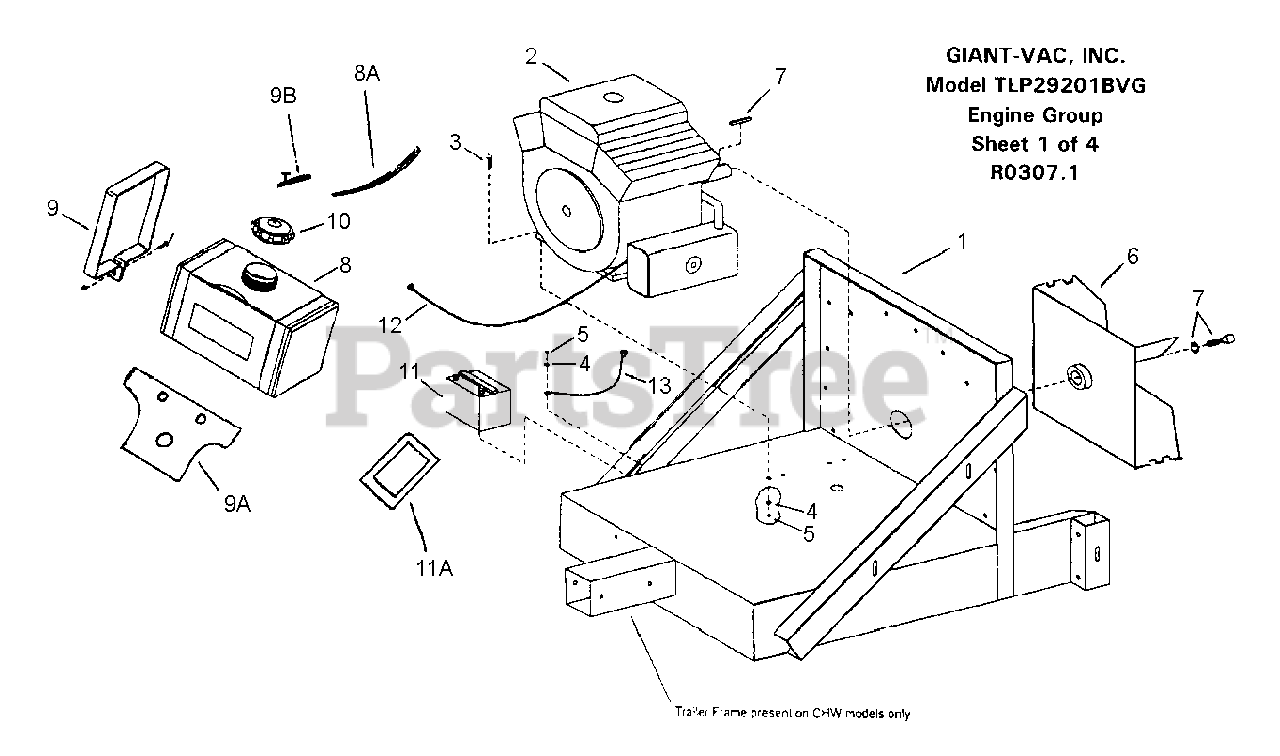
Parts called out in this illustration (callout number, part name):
1	Engine Base & Trailer Frame CHW
2	* Engine, 29HP B&S, Mod. 542477-0125-E1
3	3/8 x 2" Hex Bolt (Motor Mount Bolt)
3	3/8 x 1-3/4" Hex Bolt (Motor Mount Bolt)
4	3/8 Lock Washer
5	3/8 Hex Nut
6	Impeller, 20"
7	5/8-18 x 2" Impeller Bolt & Key Group
8	Fuel Tank
8A	Hose, Rubber Fuel 1/4" x 10" Length
9	Fuel Tank Strap
9A	Gas Tank Mount
9B	Inline Fuel Shutoff Valve
10	Fuel Tank Cap
11A	Battery Box
12	Battery Cable - 32SS (Positive)
13	Battery Cable - 16SS (Ground)
